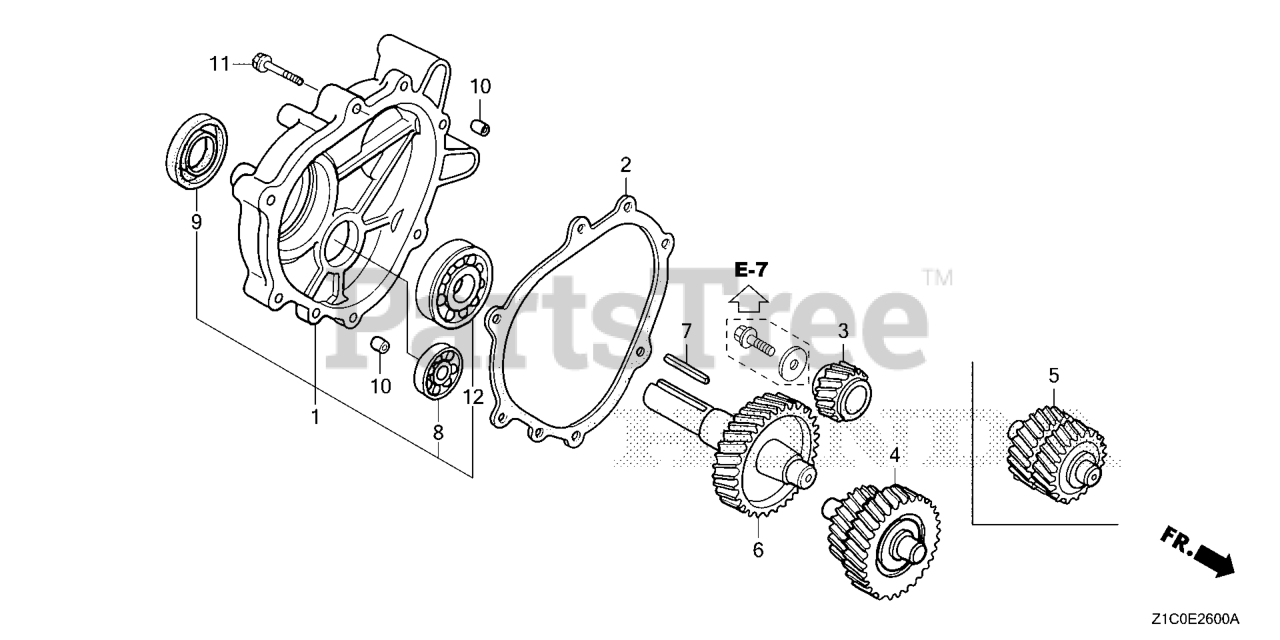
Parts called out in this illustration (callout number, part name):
1	COVER ASSY., GEAR CASE
2	GASKET, CHAIN CASE COVER
3	GEAR, PRIMARY DRIVE
4	COUNTERSHAFT
6	SHAFT, P.T.O. (L-TYPE)
7	KEY (7X7X33)
8	BEARING, RADIAL BALL (6202)
9	OIL SEAL (30X46X8) (NOK ASIA)
10	PIN A, DOWEL (8X14)
11	BOLT, FLANGE (8X40) Use up to Engine SN 1003236.
12	BEARING, RADIAL BALL (6206)
